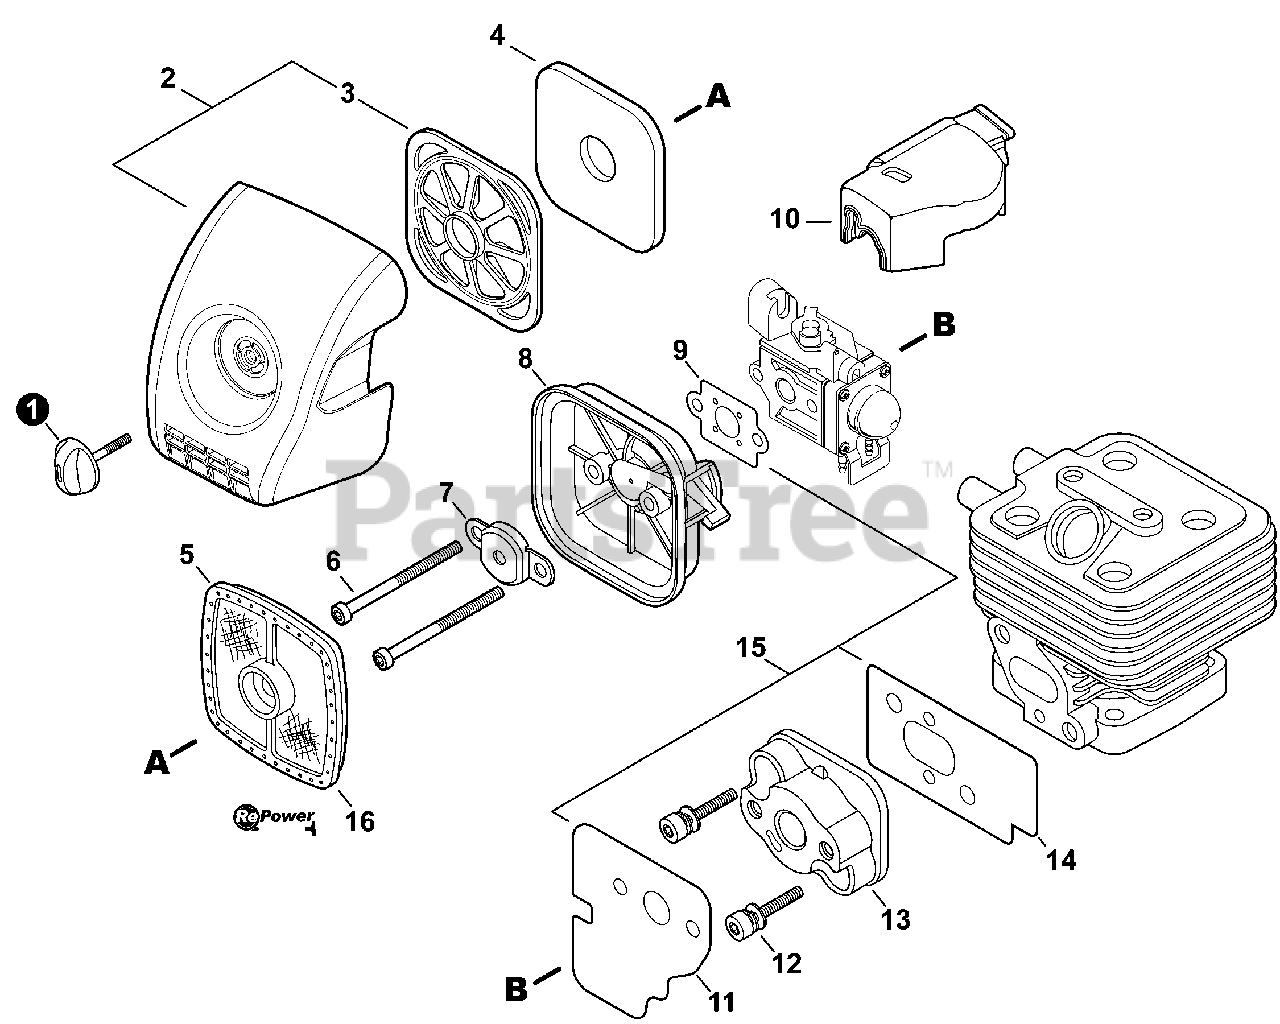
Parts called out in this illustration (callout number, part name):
1	THUMBSCREW
2	COVER KIT, AIR FILTER
3	RETAINER, PRE-FILTER
4	PRE-FILTER, FOAM
5	FILTER, AIR - DOUBLE LAYER
6	BOLT 5×60
7	PLATE, PREVENT
8	CASE ASSY, AIR FILTER
9	GASKET, INTAKE
10	COVER, DUST
11	GASKET, INTAKE
12	BOLT 5×25
13	INSULATOR, INTAKE
14	GASKET, INTAKE
15	GASKET KIT
16	TUNE-UP KIT - REPOWER
